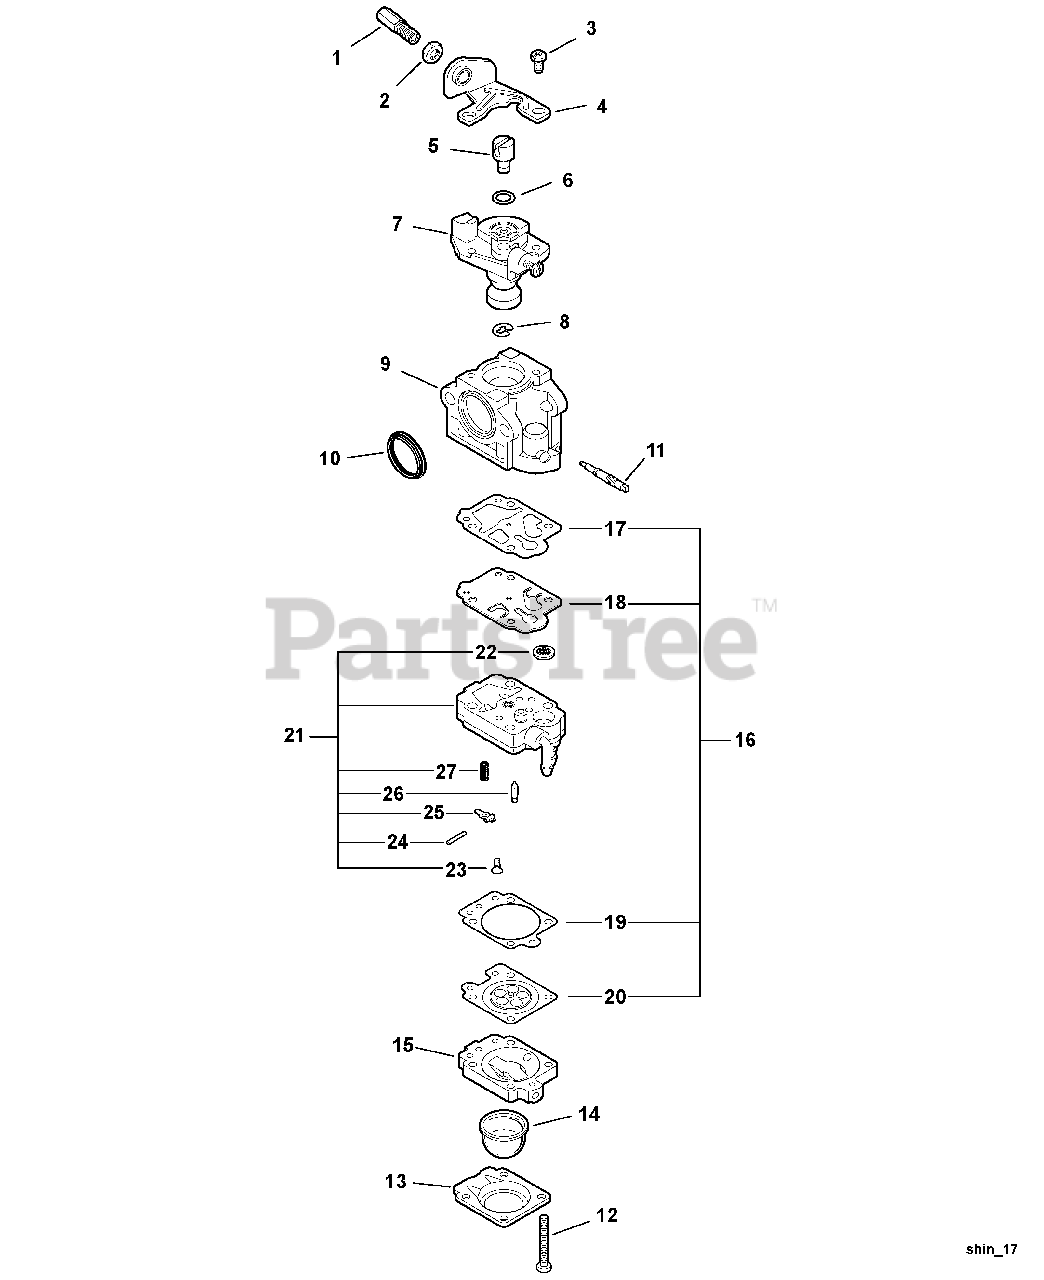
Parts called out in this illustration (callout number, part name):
1	ADJUSTER, THROTTLE CABLE
2	NUT, ADJUSTER LOCK M7
3	SCREW
4	BRACKET, THROTTLE CABLE
5	SWIVEL
6	WASHER
7	VALVE ASSY, THROTTLE
8	E-RING
9	BODY, CARBURETOR
10	RING, PACKING
11	NEEDLE, HIGH SPEED
12	SCREW
13	RETAINER, PURGE BULB
14	BULB, PURGE
15	BODY ASSY, PURGE
16	GASKET / DIAPHRAGM KIT
17	GASKET, PUMP
18	DIAPHRAGM, PUMP
19	GASKET, METERING DIAPHRAGM
20	DIAPHRAGM, METERING
21	BODY ASSY, PUMP
22	SCREEN, FUEL INLET
23	SCREW
24	PIN, METERING LEVER
25	LEVER, METERING
26	VALVE, INLET NEEDLE
27	SPRING, METERING LEVER
